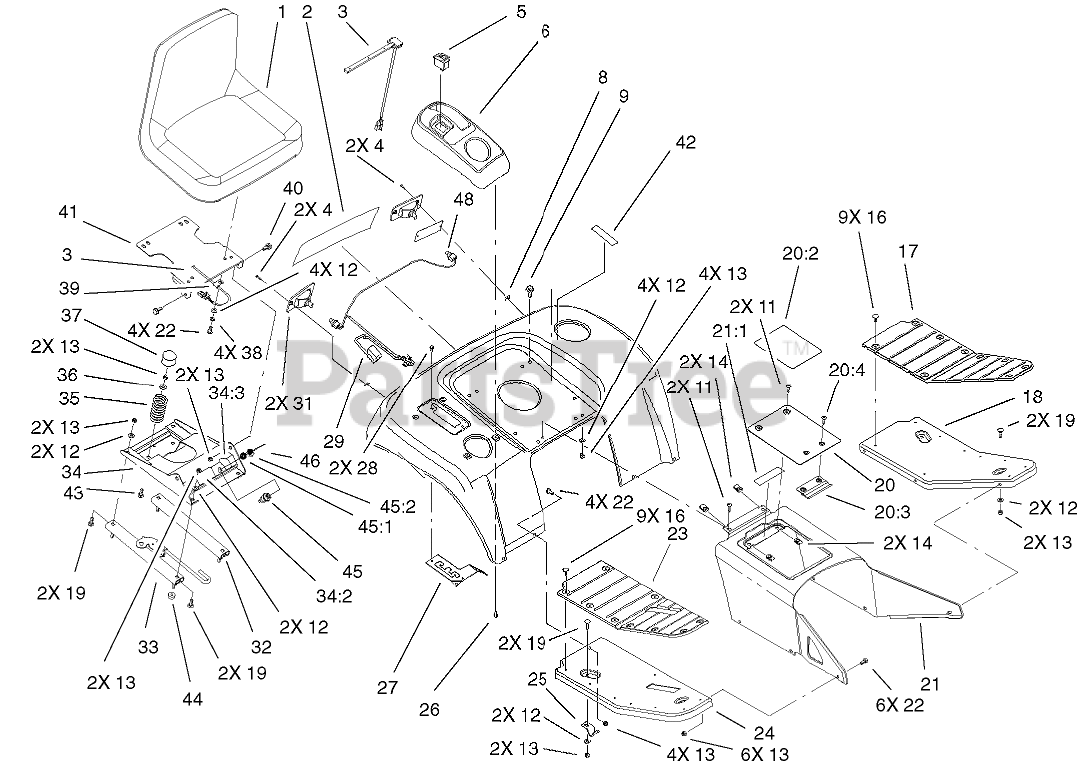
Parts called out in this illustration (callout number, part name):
1	SEAT
2	DECAL - FENDER
3	SWITCH-SEAT
4	SCREW-PPH
5	SWITCH-CRUISE
6	Pod-Control (only on: 73552)
6	Pod-Control Int-l (only on: 73590)
8	NUT-SPEED
9	SCREW-HHF
11	SCREW-HH
12	WASHER-PLAIN
13	NUT-LOCK, NI
16	FASTENER-PANEL
17	PAD-FOOTREST, LH
18	FOOTREST-LH
19	SCREW-CARR
20	Tunnel Cover ASM (only on: 73590)
20	Cover/Decal ASM (only on: 73552)
20:2	Decal-Danger (only on: 73552)
20:2	Decal-Danger (only on: 73590)
20:3	RETAINER-COVER
20:4	SCREW-PPH
21	Tunnel ASM (only on: 73552)
21	Tunnel ASM (only on: 73590)
21:1	Decal-Warning (only on: 73590)
21:1	Decal-Danger (only on: 73552)
22	SCREW-HH
23	PAD-FOOTREST, RH
24	FOOTREST-RH
25	BRACKET-FOOTREST
26	SCREW-HHFTF
27	GATE-HI / LO SHIFT
28	SCREW-HWH
29	HARNESS-REAR
31	LAMP-TAILLIGHT
32	SLIDE-SLAVE, SEAT
33	SLIDE-LATCH, SEAT
34	Seat Base ASM, Intl Decal (only on: 73590)
34	Seat Base ASM (only on: 73552)
34:2	Decal-Danger (only on: 73590)
34:2	Decal-Danger (only on: 73552)
34:3	Decal-Switch (only on: 73590)
34:3	Decal (only on: 73552)
35	SPRING-COMPRESSION
36	BUSHING
37	CAP-SPRING, SEAT
38	WASHER-LOCK
39	CLAMP-R
40	BOLT-SHOULDER
41	MOUNT-SEAT
42	DECAL - DIESEL
43	SCREW-CARR
44	WASHER-FLAT
45	STARTER SWITCH ASM
45:1	WASHER-TOOTH, INTERNAL
45:2	NUT-HH
46	KEY-IGNITION
48	LIGHT BULB
